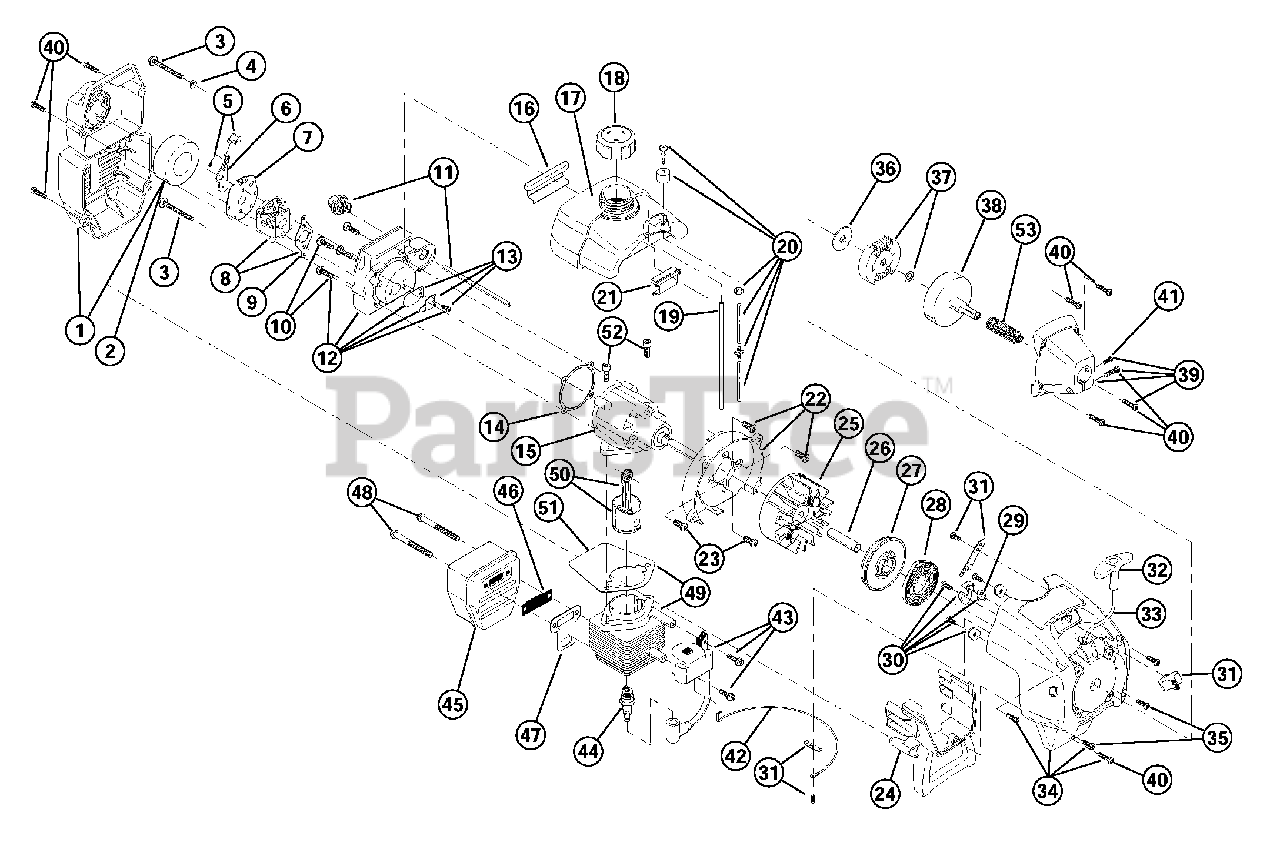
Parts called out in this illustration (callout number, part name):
1	Air Cleaner/Muffler Cover Assembly
2	Air Cleaner Filter
3	Carburetor Mounting Screw Assembly
4	Wavey Washer
5	Choke Knob and Screw
6	Choke Lever Assembly
7	Choke Lever and Plate
8	Carburetor Assembly
9	Carburetor Gasket
10	Carb Mount Screw
11	Primer and Hose Assembly
12	Carb Mount Assembly
13	Reed Assembly
14	Carburetor Mount Gasket
15	Crankcase Service Assembly
16	Rear Mounting Pad
17	Fuel Tank Assembly
18	Fuel Cap Assembly
19	Fuel Return Line
20	Fuel Line Assembly
21	Front Mounting Pad
22	Shroud Assembly
23	Shroud Screw
24	Shroud Extension and Stand
25	Flywheel Assembly
27	Recoil Pulley Assembly
28	Recoil Spring
29	Rope Guide
30	Pulley Retainer Assembly
31	Switch Assembly
32	Pull Handle
34	Starter Housing Assembly
35	Housing Screw
36	Clutch Washer
37	Clutch Rotor Assembly
38	Clutch Drum Assembly
39	Clutch Cover Assembly
41	Anit-Rotation Screw
42	Wire Lead
43	Module Assembly
44	Spark Plug
45	Muffler Assembly
46	Spark Arrestor Screen
47	Exhaust Gasket
48	Muffler Mounting Bolt Assembly
49	Cylinder Assembly
50	Piston and Rod Assembly
51	Cylinder Gasket
52	Cylinder Bolt
